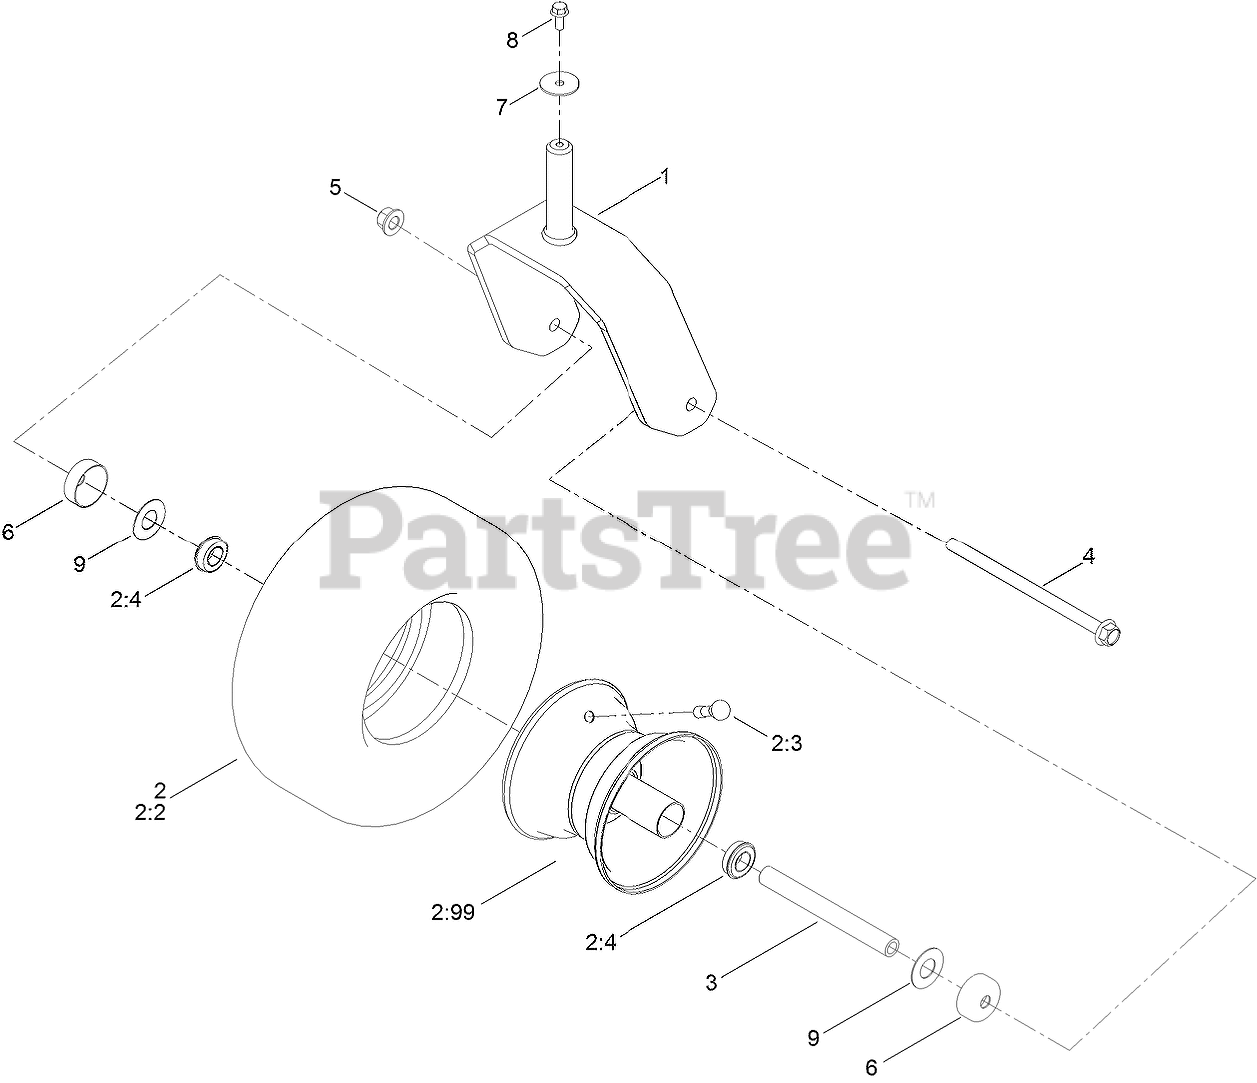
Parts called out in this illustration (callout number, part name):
1	FORK-CASTER
2	TIRE AND WHEEL ASM
2:4	BEARING
2:99	TUBE-INNER
3	SPANNER-WHEEL
4	SCREW-HHF
5	NUT-HF
6	GUARD-SEAL
7	WASHER-FLAT
8	SCREW-HHF
9	WASHER
